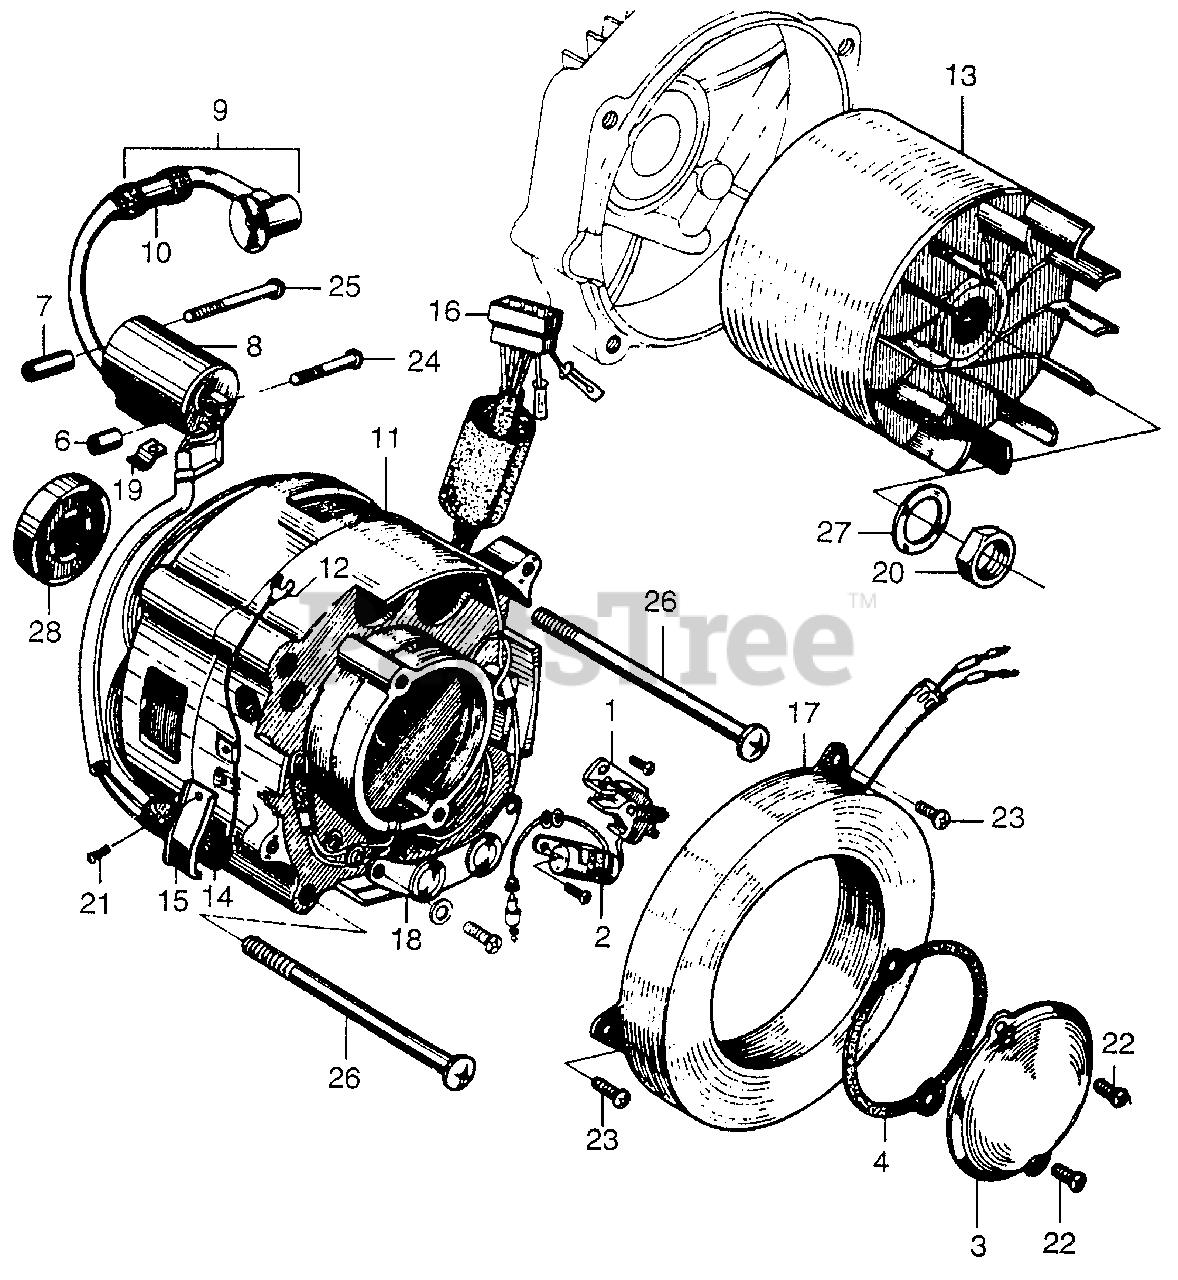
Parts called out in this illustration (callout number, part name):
1	POINTS ASSY.
2	CONDENSER ASSY. (NOT AVAILABLE)
3	COVER, POINTS
4	GASKET, POINTS COVER
6	COLLAR A, IGNITION DISTANCE
7	COLLAR B, IGNITION DISTANCE
8	COIL ASSY., A.C. IGNITION (NOT AVAILABLE)
9	TERMINAL ASSY., IGNITION (NOT AVAILABLE)
10	SUPPRESSOR, NOISE (NOT AVAILABLE)
11	STATOR ASSY., ALTERNATOR
12	TERMINAL, D.C. (5MM)
13	ROTOR, ALTERNATOR
14	TUBE A, RUBBER
15	CLAMP, JOINT
16	CONNECTOR (4P)
18	RECTIFIER, SILICON
18	RECTIFIER, SILICON (NOT AVAILABLE)
19	CLAMP, WIRE
19	CLAMP
20	NUT, SPECIAL (14MM)
21	SCREW, PAN (4X6)
22	SCREW, PAN (4X8)
23	SCREW, PAN (5X12)
24	SCREW, PAN (5X28)
25	SCREW, PAN (5X40)
26	SCREW, PAN (6X100) (NOT AVAILABLE)
27	WASHER, FLAT (14MM)
28	BEARING, RADIAL BALL (6001UU)
